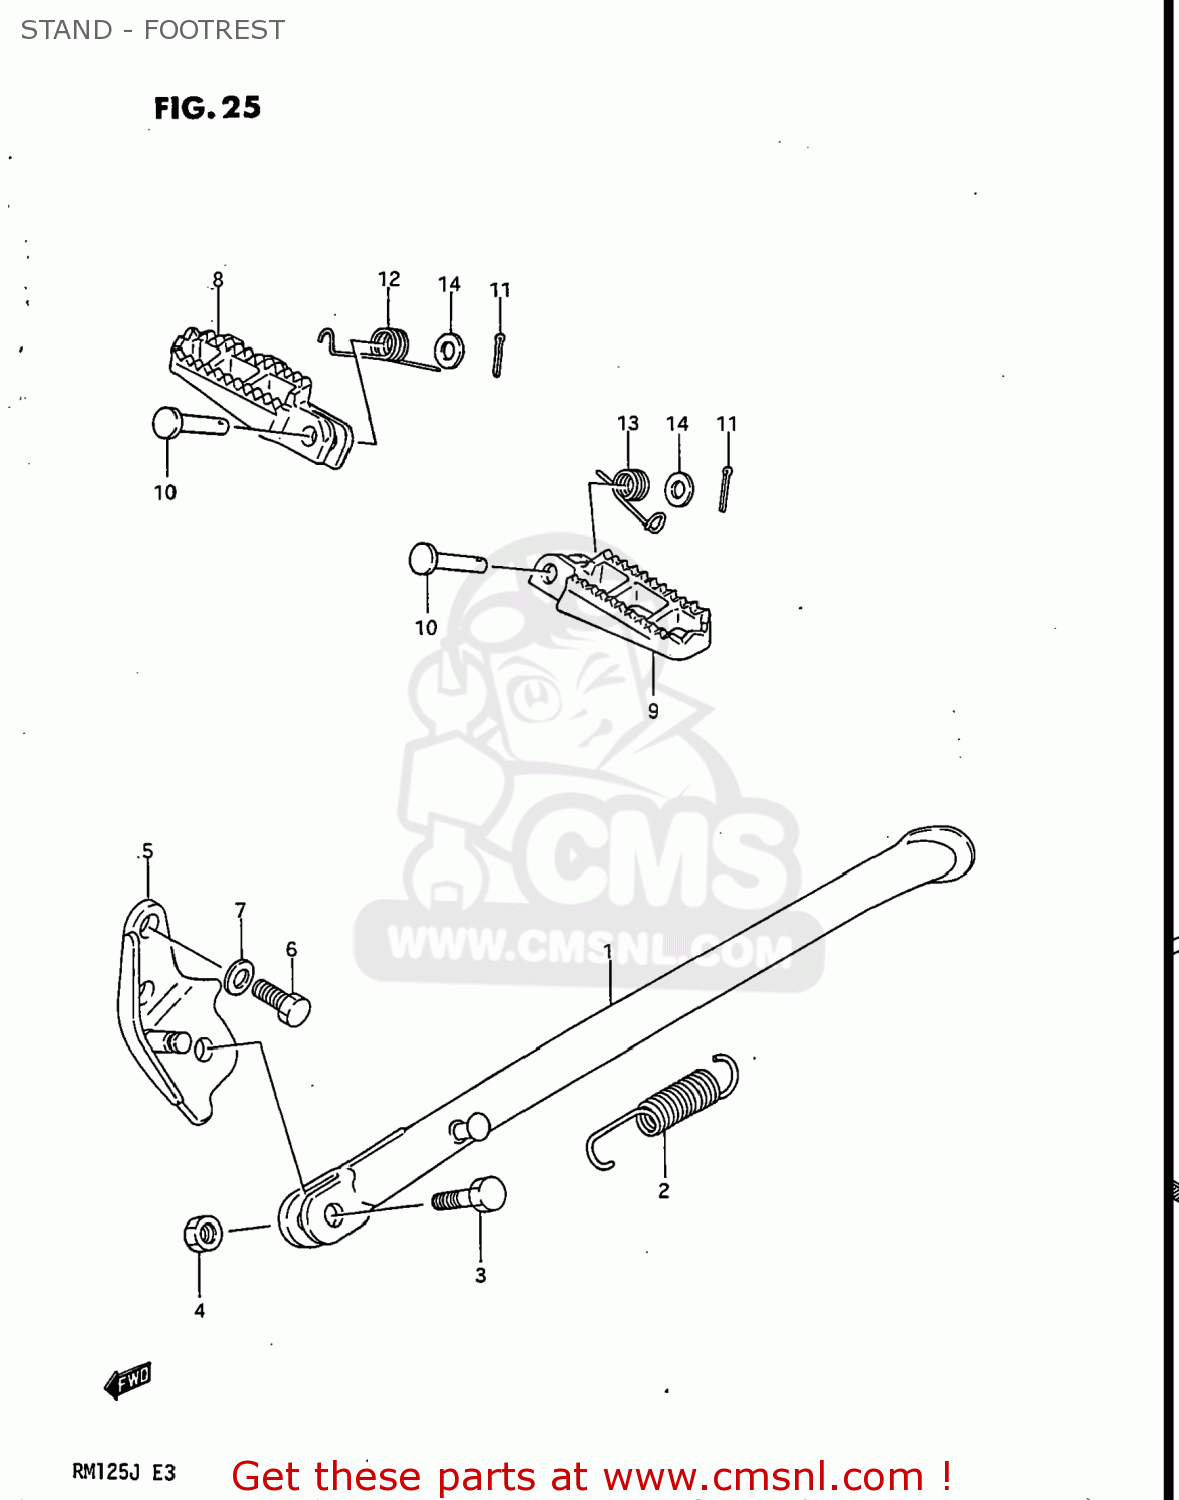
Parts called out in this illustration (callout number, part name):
1	STAND,SIDE
2	SPRING
3	BOLT(10X30)
4	NUT
5	BRACKET,SIDE STAND
6	BOLT(10X19)
7	WASHER,LOCK,10
8	FOOTREST
9	FOOTREST
10	PIN
11	PIN 20X20
12	SPRING
13	SPRING
14	WASHER
